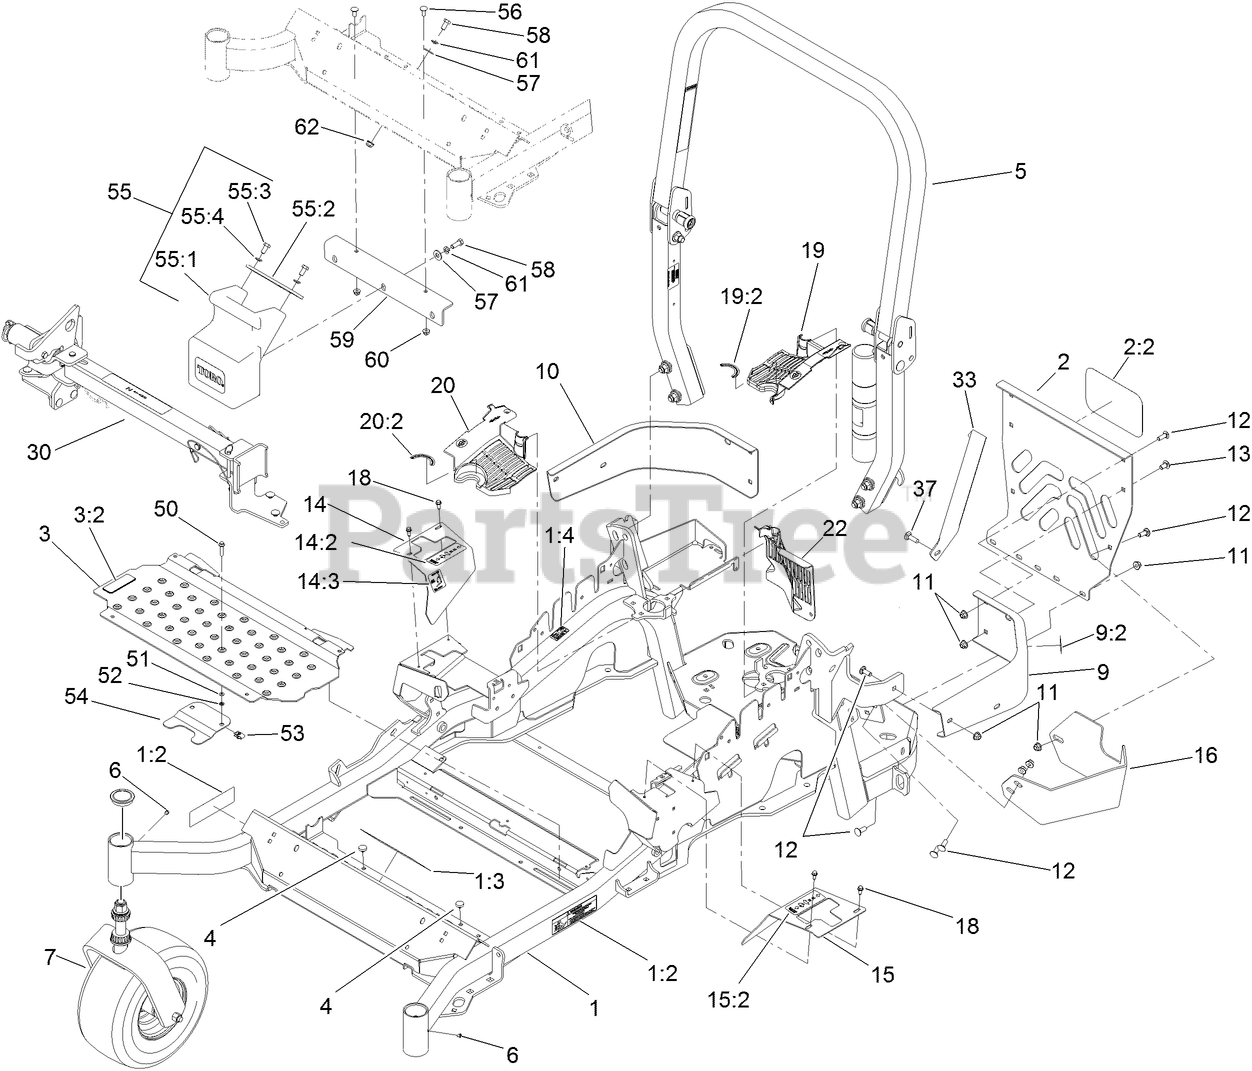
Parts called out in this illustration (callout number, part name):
1	MAIN FRAME ASM
1:2	DECAL-DANGER SLOPE W/ROPS
1:3	DECAL-WARNING
1:4	DECAL-HAZARD, PINCHED FINGER
2	REAR GUARD ASM
2:2	DECAL
3	FLOORPAN ASM
3:2	DECAL-MISSING, COVER
4	BUMPER
5	ROPS ASM
7	FRONT CASTER ASM
9	LH REAR BUMPER ASM
9:2	DECAL-WARNING
10	BUMPER-RH
11	NUT-HF, NI
12	SCREW-CARR
13	SCREW-CARR
14	RH MOTION CONTROL COVER ASM
14:2	DECAL-CONTROL, MOTION
14:3	DECAL-PARKING BRAKE
15	LH MOTION CONTROL COVER ASM
15:2	DECAL-CONTROL, MOTION
16	GUARD-MUFFLER
18	SCREW-HWH
19	LH HYDRO GUARD ASM
19:2	DECAL-HYDRO OIL
20	RH HYDRO GUARD ASM
20:2	DECAL-HYDRO OIL
22	GUARD-HYDRO, REAR (RH)
30	Z STAND ASM
37	BOLT-CARR
50	SCREW-HHF
51	WASHER-FLAT
52	NUT-RETAINER
54	ADAPTER-CAPTIVE
55	WEIGHT ASM
55:1	WEIGHT-43 LB
55:2	TAB-SUPPORT, WEIGHT
55:3	SCREW-HH
55:4	WASHER-LOCK
56	SCREW-CARR
57	WASHER-FLAT
58	SCREW-HH
59	BRACKET-MOUNT, WEIGHT
60	NUT-HF, NI
61	WASHER-LOCK
62	NUT-HF, NI
